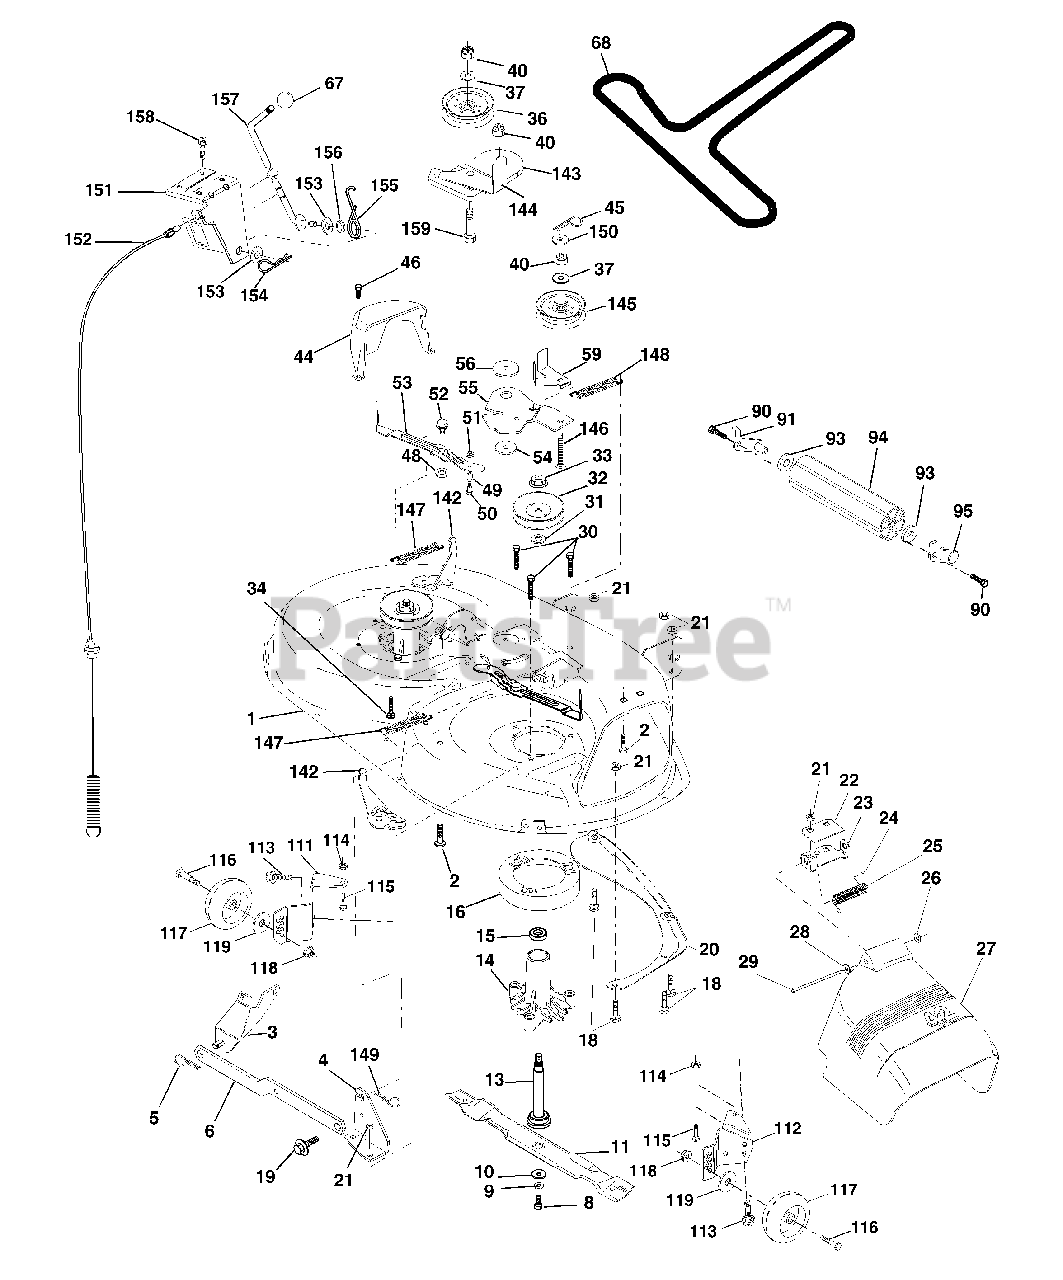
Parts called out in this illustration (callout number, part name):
1	Mower Deck Assembly, 42"
2	Bolt
3	Bracket Asm Fr. Sway Bar 3/42
4	Bracket Asm Deck 42" Sway Bar
5	Retainer Spring
6	Arm, Suspension, Rear
8	Bolt 3/8-24 x 25 Grade 8 patched
9	Washer, Lock
10	Washer, Hardened
11	Blade
13	Shaft Assembly, Mandrel, Vented
14	Housing, Mandrel, Vented
15	Bearing, Ball, Mandrel
16	Stripper, Mower Deck
18	Bolt, Carriage 5/16-18 x 5/8
19	Bolt, Shoulder
20	Baffle, Vortex
21	Nut
22	Stiffener Bracket
23	Bracket, Deflector Mower 42"
24	Cap, Sleeve 80 x 112 Blk Mower
25	Spring, Torsion, Deflector 2 52
26	Nut, Push Phos & Oil
27	Shield, Deflector 42" Blk
28	Washer 11/32 x 5/8 x 16 Gauge
29	Rod, Hinge 42" 6 75 W/G
30	Screw Thdrol Washer Head
31	Washer, Spacer Mower Vented
32	Pulley, Mandrel
33	Nut, Toplock
34	Bolt
36	Pulley, Idler, Flat
37	Washer 13/32 x 13/16 x 16 Gauge
40	Nut
44	Guard, Mandrel, LH
45	Retainer
46	Screw, Thdrol 1/4-20 x 5/8 T
48	Washer, Hardened
49	Roller Assembly, Cam Follower
50	Bolt, Shoulder #10-24 Grade 5
51	Locknut
52	Bolt, Shoulder 5/16-18 UNC
53	Arm Assembly, Pad, Brake
54	Washer, Hardened
55	Arm, Idler
56	Spacer, Retainer
59	Guard TUV Idler
67	Knob
68	V-Belt, 42" Mower
90	Screw 3/8-16 x 3/4
91	Bracket Asm Noseroller Lh
93	Washer 17/32 x 7/8 x 16 Ga.
94	Roller Nose 38-50"
95	Bracket Asm. Noseroller Rh
111	Bracket Gauge Wheel Lh
112	Bracket Gauge Wheel Rh
113	Screw 5/16-18 x 1/2
114	Nut Keps 5/16-18unc
115	Bolt Carr 5/16-18 x 5/8
116	Bolt Shld
117	Wheel Gauge Blk
118	Nut Centerlock 3/8-16unc
119	Washer 3/8 x 7/8 x 14 Ga.
142	Arm Spring Brake Mower
143	Bracket Arm Idler 42"
144	Keeper Belt 42" Clutch Cable
145	Pulley Idler Flat
146	Bolt Carriage Idler
147	Spring Extension
148	Spring Return Idler
149	Retainer Spring Yellow
150	Washer 9/32 x 3/4 x 16 Ga.
151	Bracket Clutch Cable
152	Clutch Cable 42"
153	Washer Flat 3/8" Type B
154	Spring Retainer
155	Spring Retention LVR CLTCH CAB
156	Spacer Clutch Cable
157	Rod Clutch Cable 3/8"
158	Screw Hex Thd Cut 1/4-20 x 5/8
159	Bolt Rdhd Sqn 3/8-16 UNC x 1-3/4
